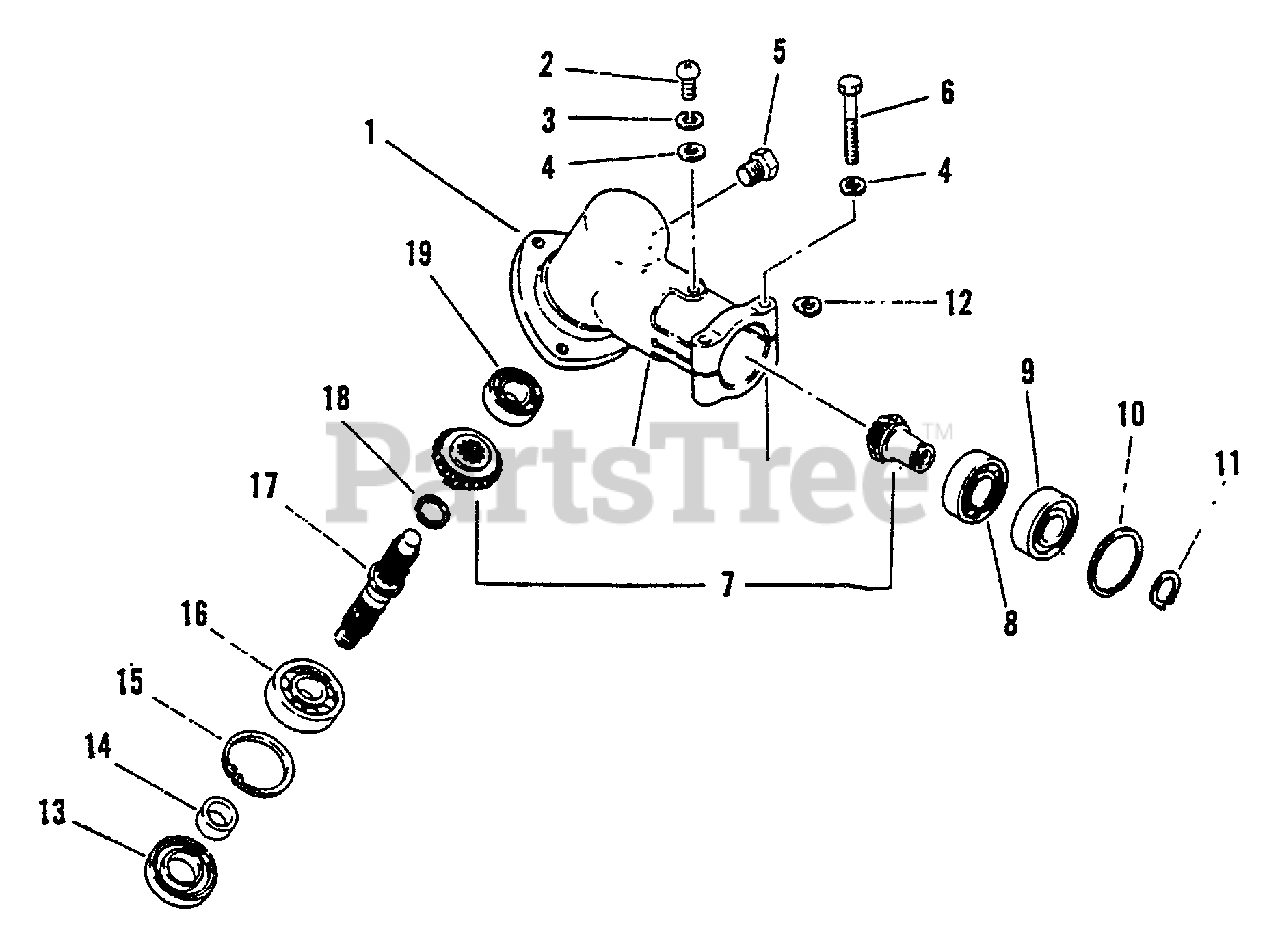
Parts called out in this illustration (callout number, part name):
1	CASE, GEAR
2	SCREW 5×10
3	WASHER, SPRING 5
4	WASHER, FLAT 5.5×10×0.8
5	BOLT 8×8 SP
6	BOLT 5×35 SP
7	GEAR SET
8	BEARING, BALL 6900
9	BEARING, BALL 6900Z
10	RING, SNAP Ø22
11	RING, SNAP Ø12
13	SEAL, OIL 22
14	SPACER 11.8×15×9
15	RING, SNAP Ø32
16	BEARING, BALL - 6201 C3
17	SHAFT, GEAR
18	RING, SNAP Ø10
19	BEARING, BALL 609
